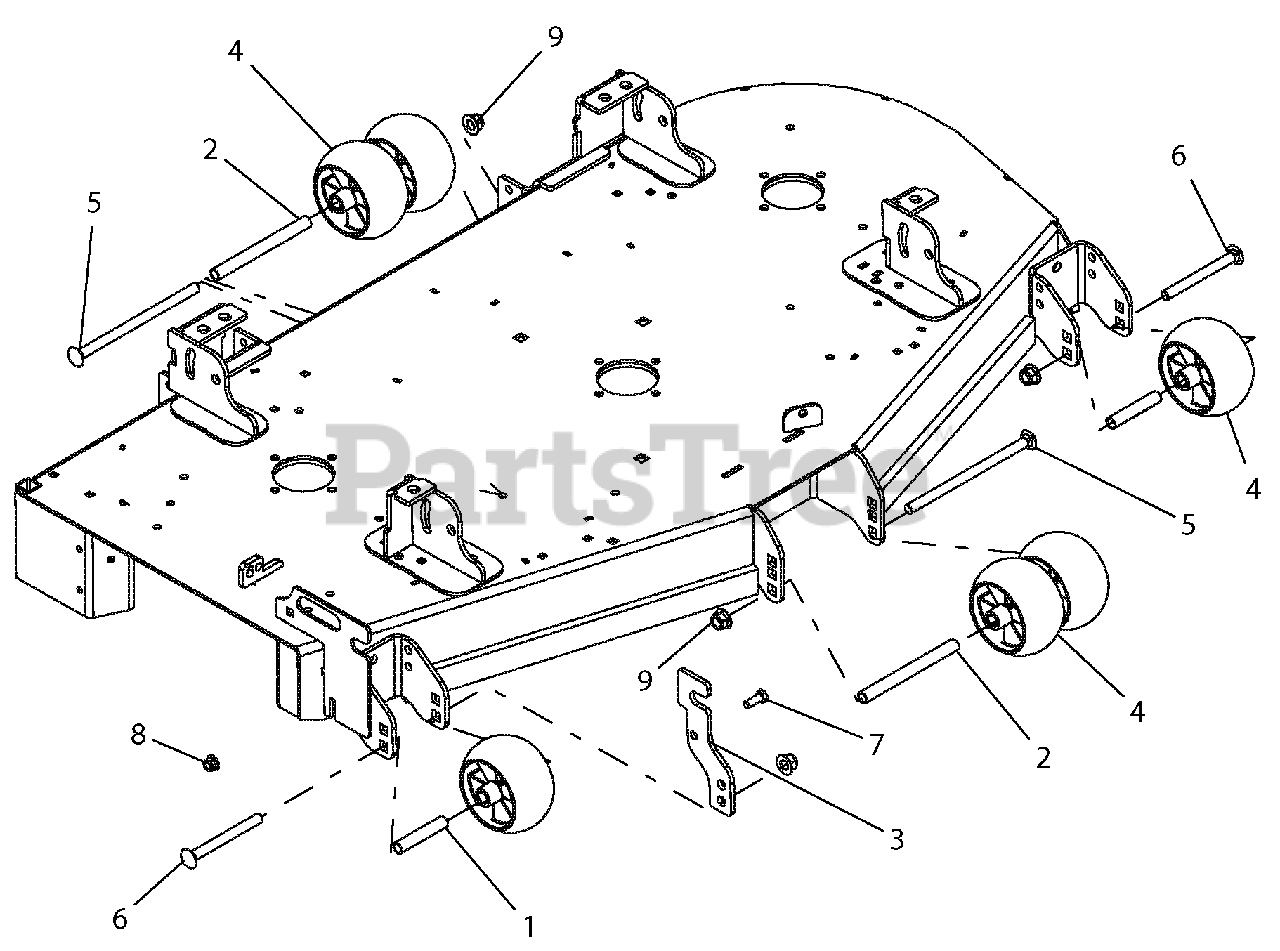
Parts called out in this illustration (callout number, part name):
1	SPACER, .510X.625X3.35
2	SPACER, .510 X .625 X 6.50
3	CHUTE STORAGE BRACKET-RED
4	ANTI-SCALP WHEEL - 5X3 CTR
5	BLT-RDHDSQNK .50-13X8.50 Y
6	BLT-RDHDSQNK .50-13X5.00 G5 YWZC
7	BLT-HEX .38-16X1.00 GR5 YWZC
8	NUT-LK-NYL-FLG .38-16 YWZC
9	NUT-LK-NYL-FLG .50-13 YWZC
